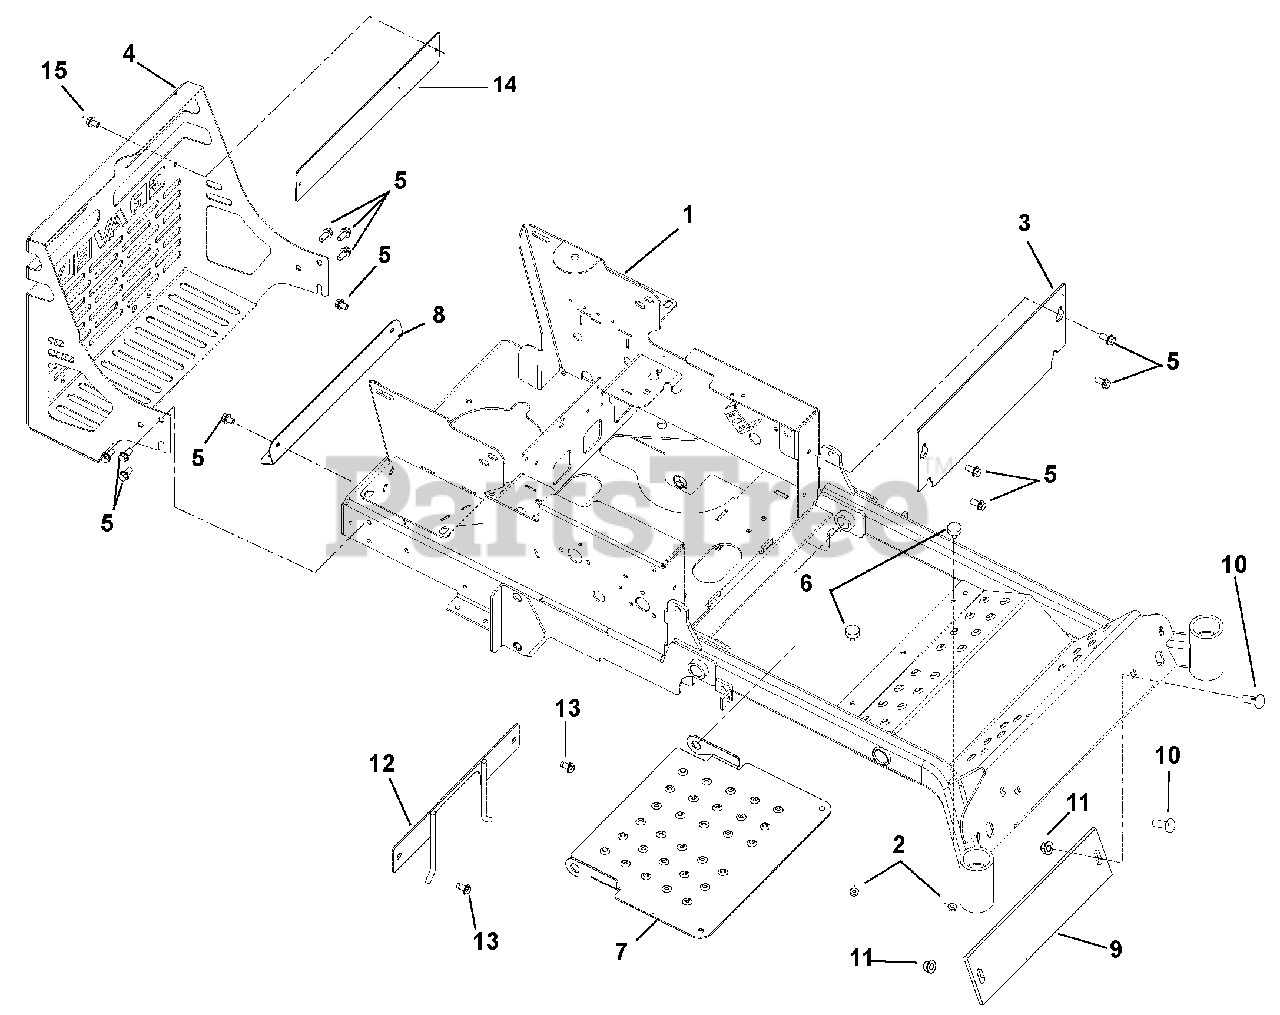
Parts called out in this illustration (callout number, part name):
1	Weldment, 44"HD Frame
2	Nut, Spin Lock Flange .312-18
3	Kick Plate
5	Screw, Tapping .38-16 x .75 Hex Washer Head
6	Bumper, Rubber
7	Panel, Inspection
8	Heat Shield
9	Counterweight CZ Front
10	Bolt, Round Head Square Neck .50-13 x 1.25 Grade 5
11	Nut .50-13 Nyloc Flange
12	Weldment, PTO Belt Finger
13	Screw, Tapping .38-16 x .75 Hex Washer Head Thread
14	Bumper Backing Plate
15	Screw, Tapping .25-20 x .50 Hex Washer Head
